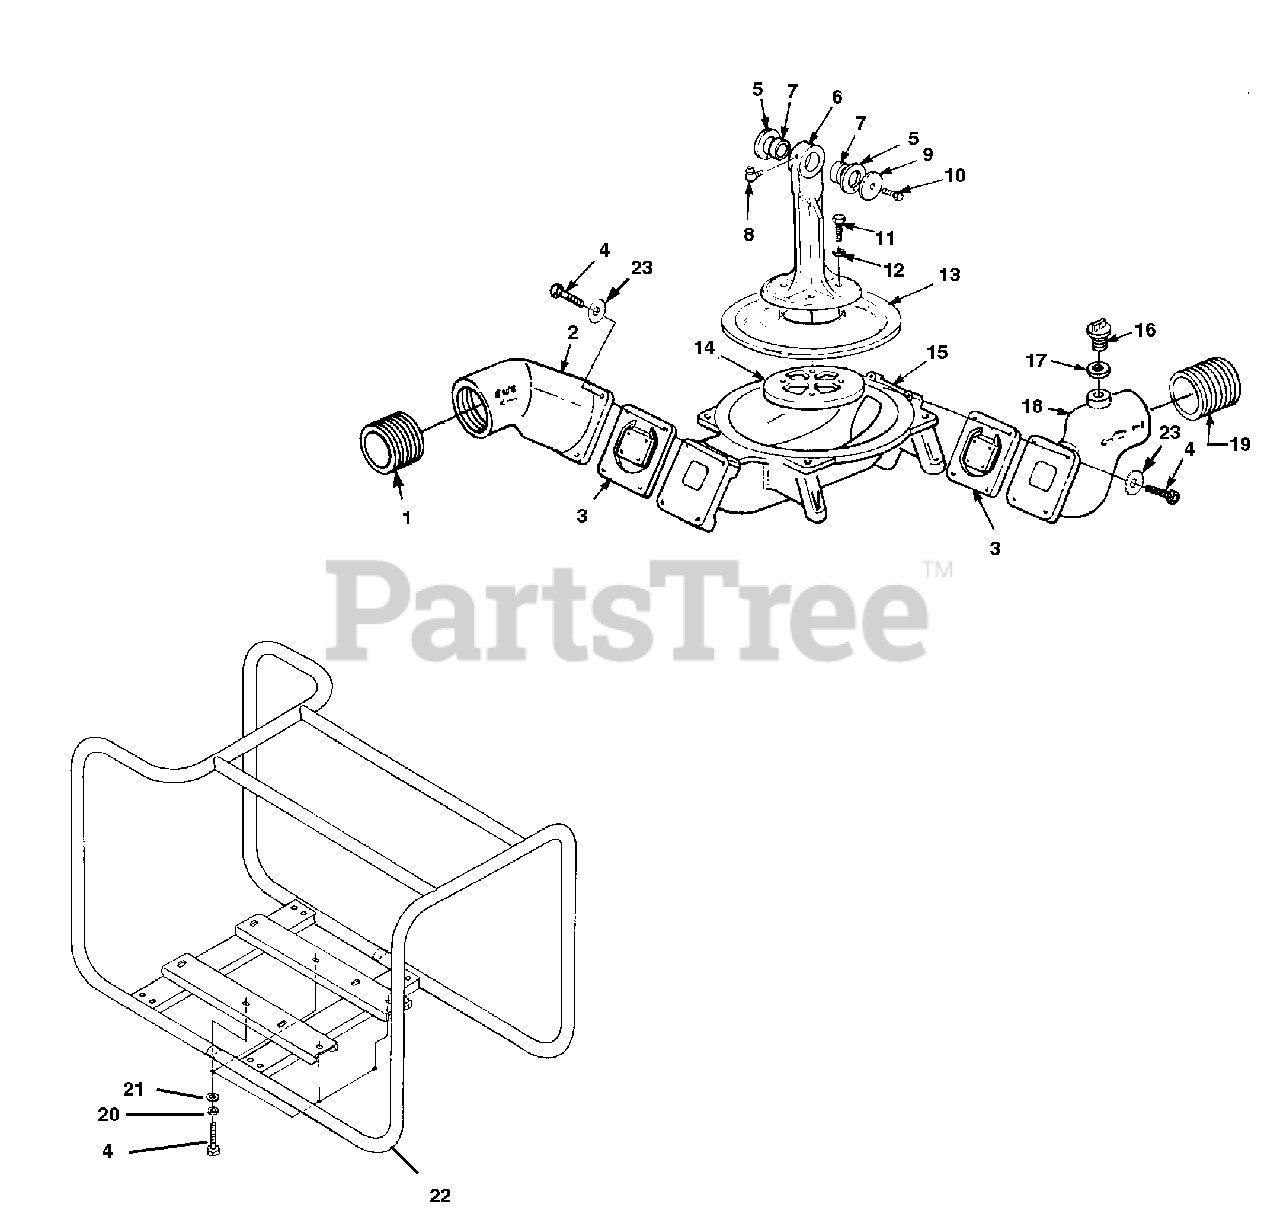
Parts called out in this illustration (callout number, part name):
1	FITTING - Pipe
2	FITTING - Discharge
3	VALVE AND INSERT
4	SCREW, Hex hd., (5/16-18 x 1")
5	WASHER - Thrust, large
6	PUMP ROD
7	BEARING - Needle
8	FITTING - Grease
10	SCREW, hex hd., 3/8-16 x 3/4
11	SCREW, hex hd., 3/8-16 x 1"
12	WASHER - Lock (3/8")
13	DIAPHRAGM
14	CAP - Diaphragm
15	BODY - Pump (lower)
16	PLUG - Filler
18	FITTING - Suction
19	FITTING - Pipe
20	WASHER - Lock (5/16")
21	WASHER - Flat (5/16")
22	ROLL CAGE
23	WASHER - Lock (5/16")
